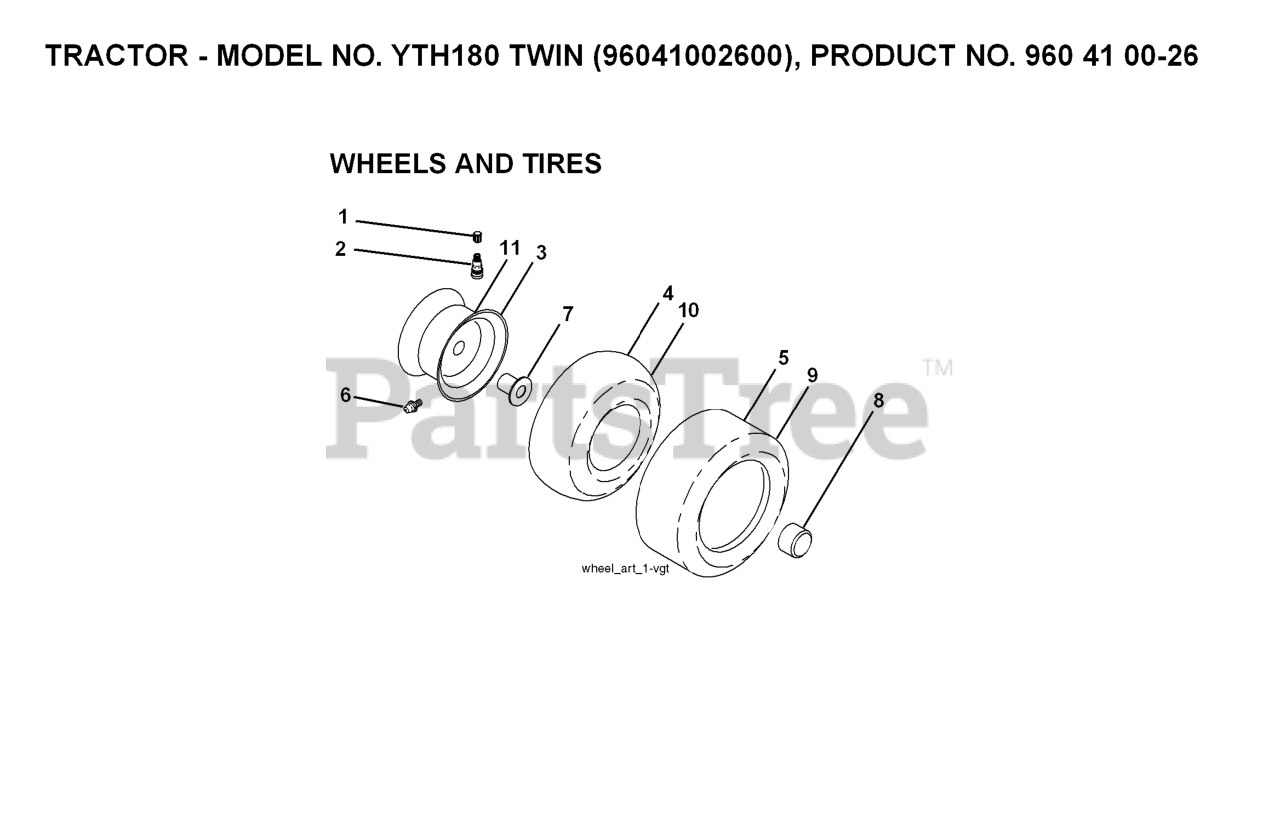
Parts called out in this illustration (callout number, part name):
2	VALVE STEM LT
3	RIM ASM 6" FRONT SILVER
4	TUBE.5.3/4.5/6
5	TIRE HEAVY DUTY
6	FITTING LT
7	BEARING T
8	CAP, AXLE BLK
9	TIRE.TS.20X10-8
10	TUBE.23X9.5-12
11	RIM ASM 8" REAR SILVER
